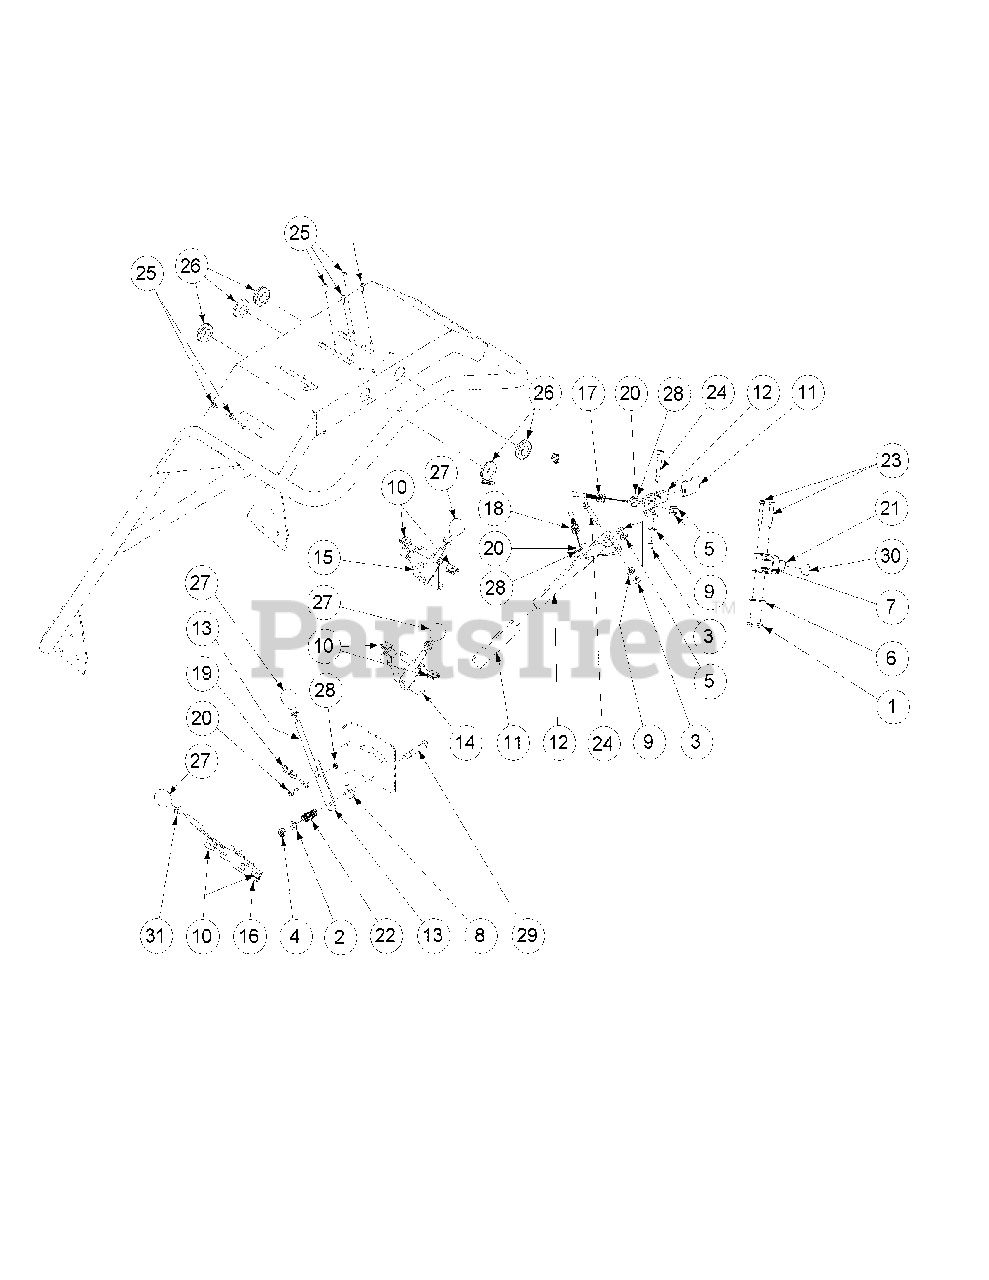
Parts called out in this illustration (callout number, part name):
1	Nut, #10-24
2	Washer, 5/16
3	Nut, 1/4-20
4	Nut, 5/16-18
5	Washer, 5/16
6	Washer, 3/16
7	Washer, 1/4, SS
8	Idler Washer
9	Washer, 1/4 x .630 x .0515
10	U-Nut, #10-16
12	Control Lever Weldment
13	On/Off Lever Weldment
14	3rd Hole Control
15	Remote Deflector Cable
16	Throttle Control
17	Forward Cable 74.25" LG
18	Reverse Cable 94.25" LG
19	On/Off Cable
20	Shoulder Bolt, 1/4 x 1/4
21	Speed Control Lever
22	Compression Spring
23	Shoulder Bolt, 1/4 x 1.25
24	Shoulder Bolt, 5/16 x 1.50
25	Hex Cap Screw, 10-24 x .50
26	Rubber Grommet
27	On/Off Lever Knob
28	Nut, 10-24, w/Star Washer
29	Shoulder Bolt 3/8 x 1.50
30	Speed Control Grip
31	Jam Nut, 3/8-16
